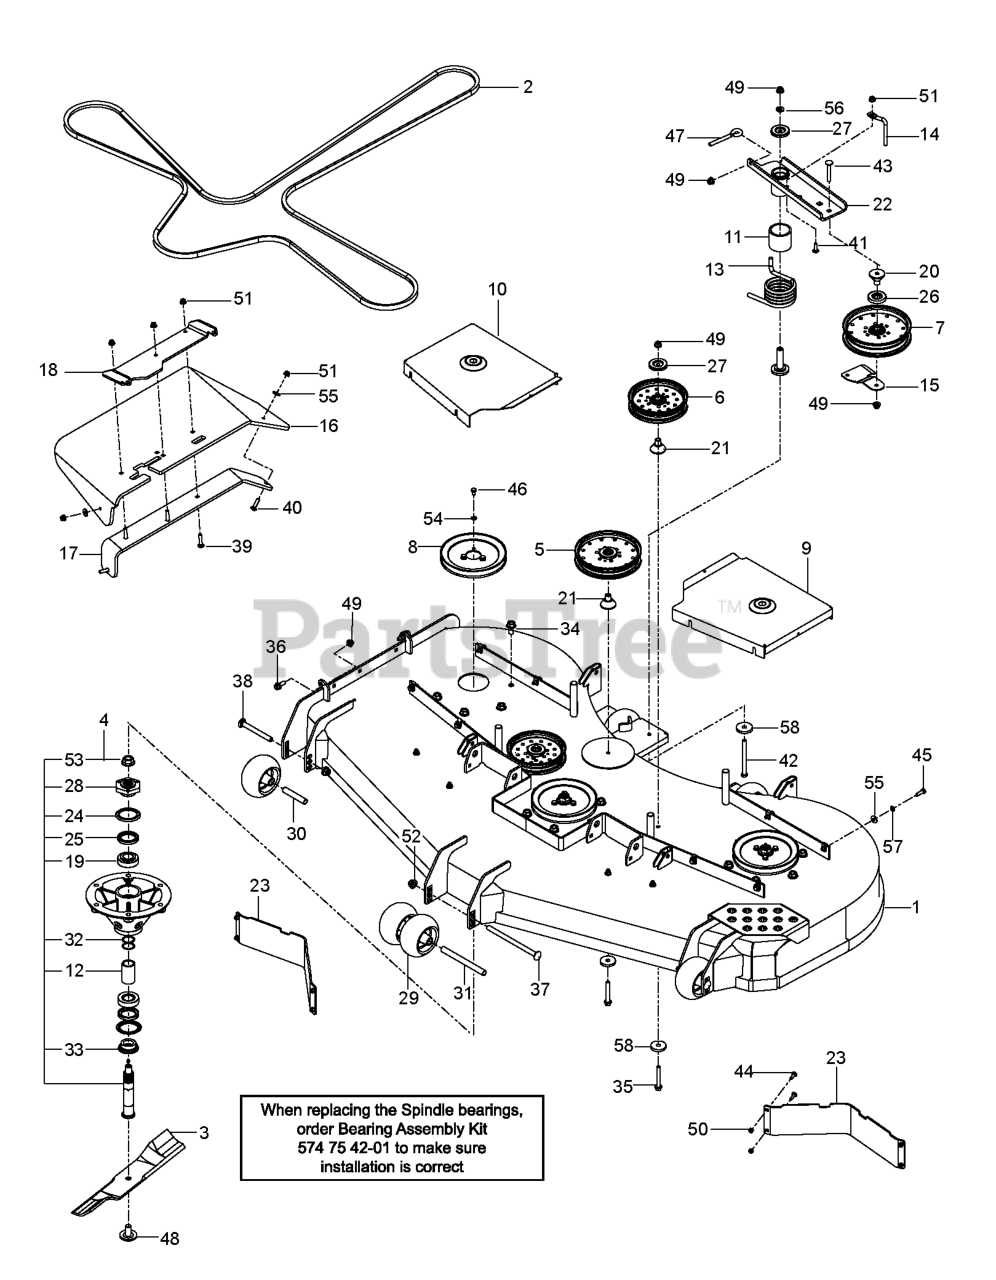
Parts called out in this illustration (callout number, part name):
1	DECK SVC W/DECALS PZ 72"
2	RP.BELT, "5V", 201"
3	BLADE OEM - 25"
4	RP_SPINDLE.ASM.10".IRON.1/8-27
5	PULLEY - 7" NARROW
6	PULLEY IDLER, 6" NARROW
7	PULLEY - IDLER 7"
8	PULLEY - 7.50
9	SHIELD, BELT 72 R.H. ORANGE
10	SHIELD, BELT 72 LH ORANGE
11	SPACER, IDLER PIVOT
13	SPRING, TORSION, IDLER
14	BELT KEEPER
15	BELT.GUIDE.BLACK
16	CHUTE, DISCHARGE 60-72
17	BRKT - CHUTE SUPPORT BLACK
18	BRKT - CHUTE MTG BLACK
19	BEARING
20	BEARING, IDLER ARM
21	BEARING, IDLER PIVOT
22	ASSY, IDLER ARM, PZ
23	BAFFLE, DIVERTER 72" BLACK
24	SEAL V-RING 55MM
25	SEAL SHAFT
26	SHIELD, DUST
27	DUST SHIELD
29	ROLLER, GAUGE .635 BORN
30	TUBE, ROLLER AXLE
31	TUBE, ROLLER AXLE LONG
34	HHFS 1/2-13 X 1 GR5 ZD
35	HHFS 3/8-16 X 2-3/4 GR5 ZD
36	HHFS 3/8-16 X 1 GRD 5 ZD
37	RHSNB 1/2-13 X 8 GR5 ZD
38	RHSNB 1/2-13 X 4.75 GR5 ZD
39	RHSNB 5/16-18 X 1-1/2 GR 5 ZD
40	BOLT, CARRIAGE 5/16X1-1/4
41	BOLT CRT
42	HCS 3/8-16 X 4-1/2 GR 8 ZD
43	CARRIAGE BOLT 3/8-16 X
44	1/4-20X3/4 CARR BLT
45	BOLT.FIN.HEX.5/16-18UNC X 1.00
46	HCS 5/16-18 X 1/2 GR 5 ZD
47	EYE BOLT, 3/8 X 4"
48	BLADE BOLT/WASHER
49	NUT 3/8-16 HEX FLG NYLOC ZD
50	NUT.1/4-20.HEX.NYLOC.ZD
51	5/16-18 NYLOC FLANGE NUT
52	NUT, 1/2-13 HEX FLG NYLOC ZD
53	NUT FLANGE 3/4-16
54	WASH 5/16 DISC SPRING ZD
55	WASHER.5/16.FLAT.STE.STD.
56	WASHER, 3/8 THICK
57	WASH.5/16.SLW.ZD
58	SPINDLE WASHER
